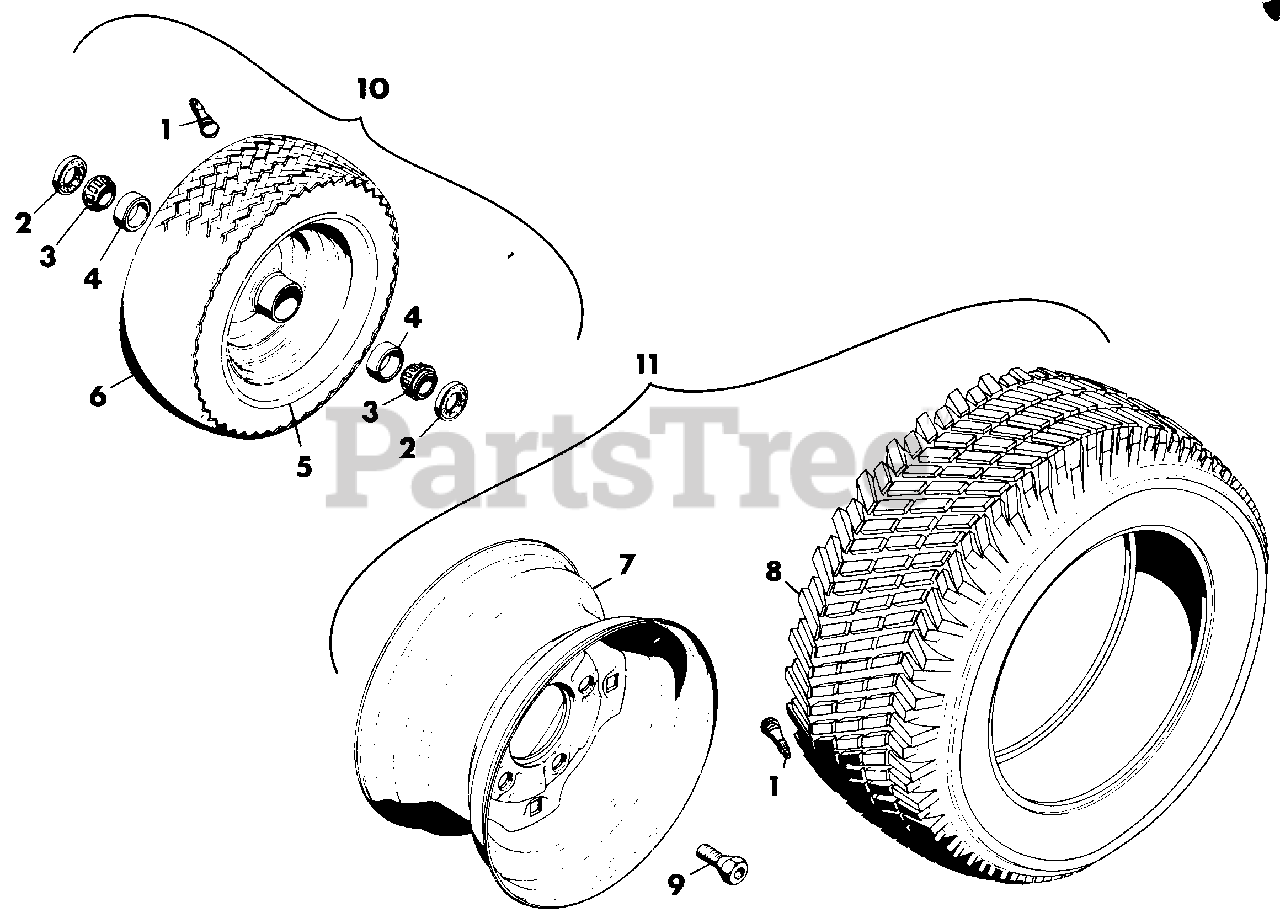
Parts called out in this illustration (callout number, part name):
1	ASSEMBLY, VALVE STEM
2	SEAL, WHEEL
3	BEARING, CONE
4	BEARING, CUP
5	RIM, REAR
6	TIRE, 16X7.50-8
7	RIM, PRO MASTER
8	TIRE, 20X10.00-10
9	STUD, WHEEL
10	WHEEL, REAR PRO MASTER
11	WHEEL, FRONT PRO MASTER
